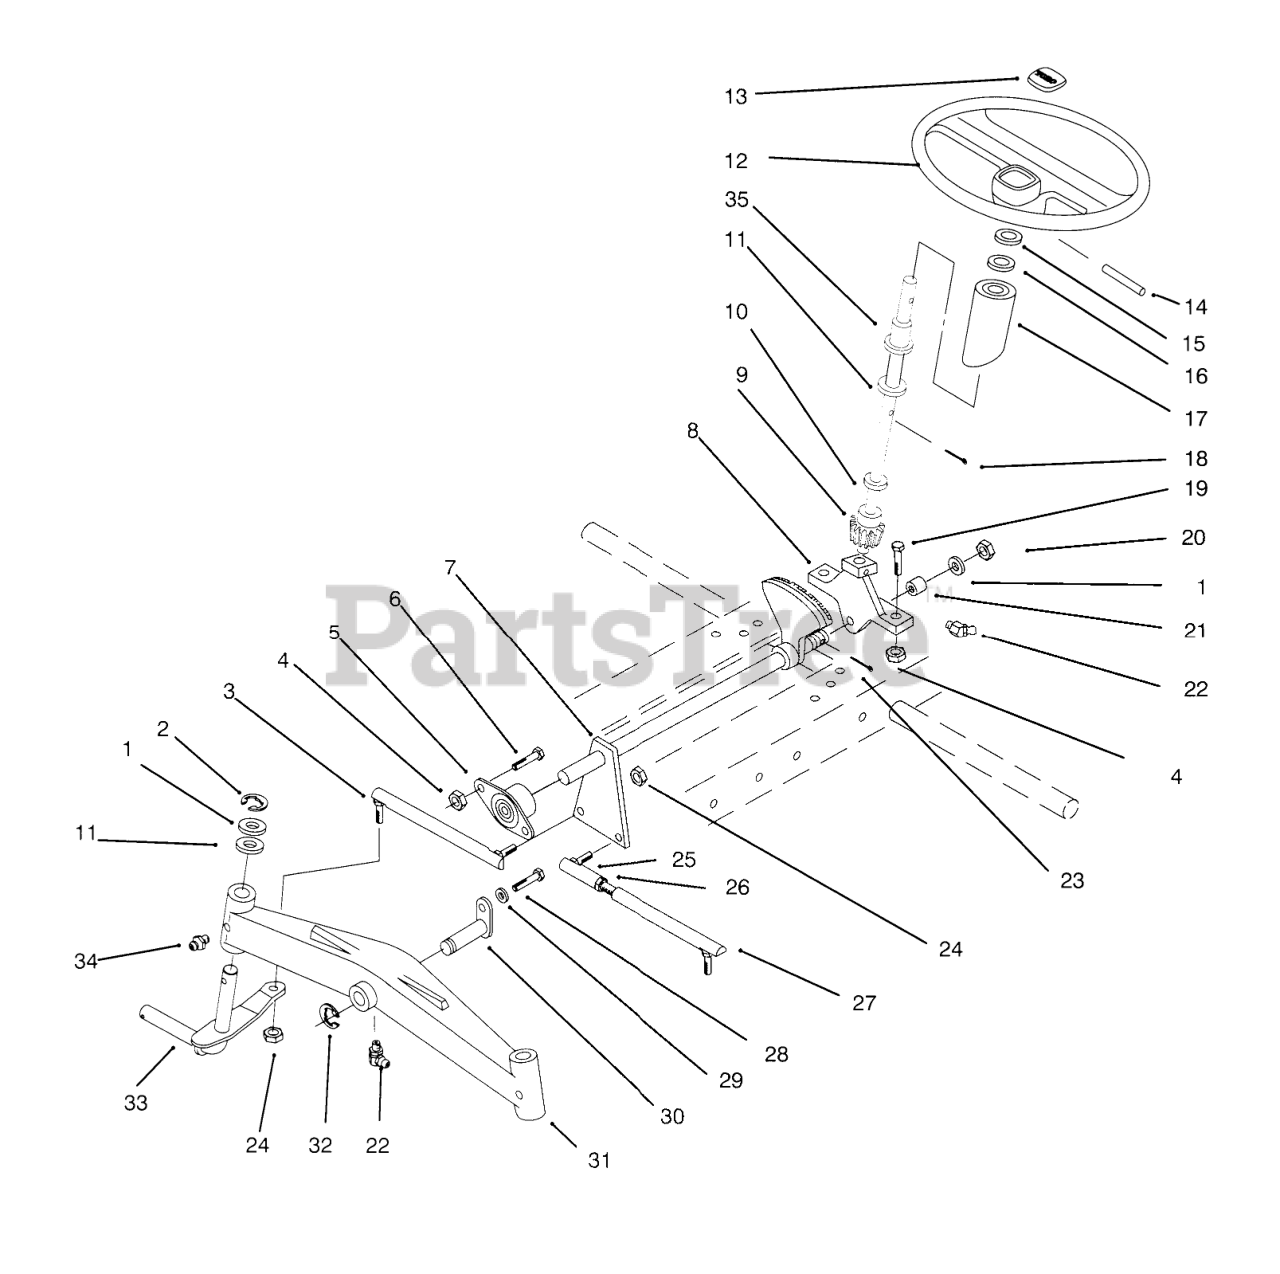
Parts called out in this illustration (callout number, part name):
1	WASHER
2	RING-RETAINING
3	Tie Rod RH
4	NUT-LOCK, NI
5	BEARING-FLANGED
6	SCREW-HH
7	Shaft
8	Support-Steering
9	STEERING SHAFT ASM
10	O-RING
11	WASHER-SHIM
12	Steering Wheel (Incl. Ref. #13)
13	STRG-WHL INSERT TORO
14	PIN-ROLL
15	WASHER-BOWED
16	WASHER-FLAT
17	TUBE-STEERING
18	PIN-COTTER
19	SCREW-HH
20	NUT-HEX, SLOTTED
21	BEARING-BRONZE
22	FITTING-GREASE
23	PIN-COTTER
24	NUT-LOCK
25	BALL-JOINT
26	NUT-HEX
27	Tie Rod Assembly, LH (Incl. Ref. #25 & 26)
28	SCREW-HH
29	WASHER-LOCK
30	PIN AND PLATE ASM
31	AXLE-FRONT
32	E-RING
33	LH SPINDLE ASM
34	FITTING-GREASE
35	BEARING-FLANGED
